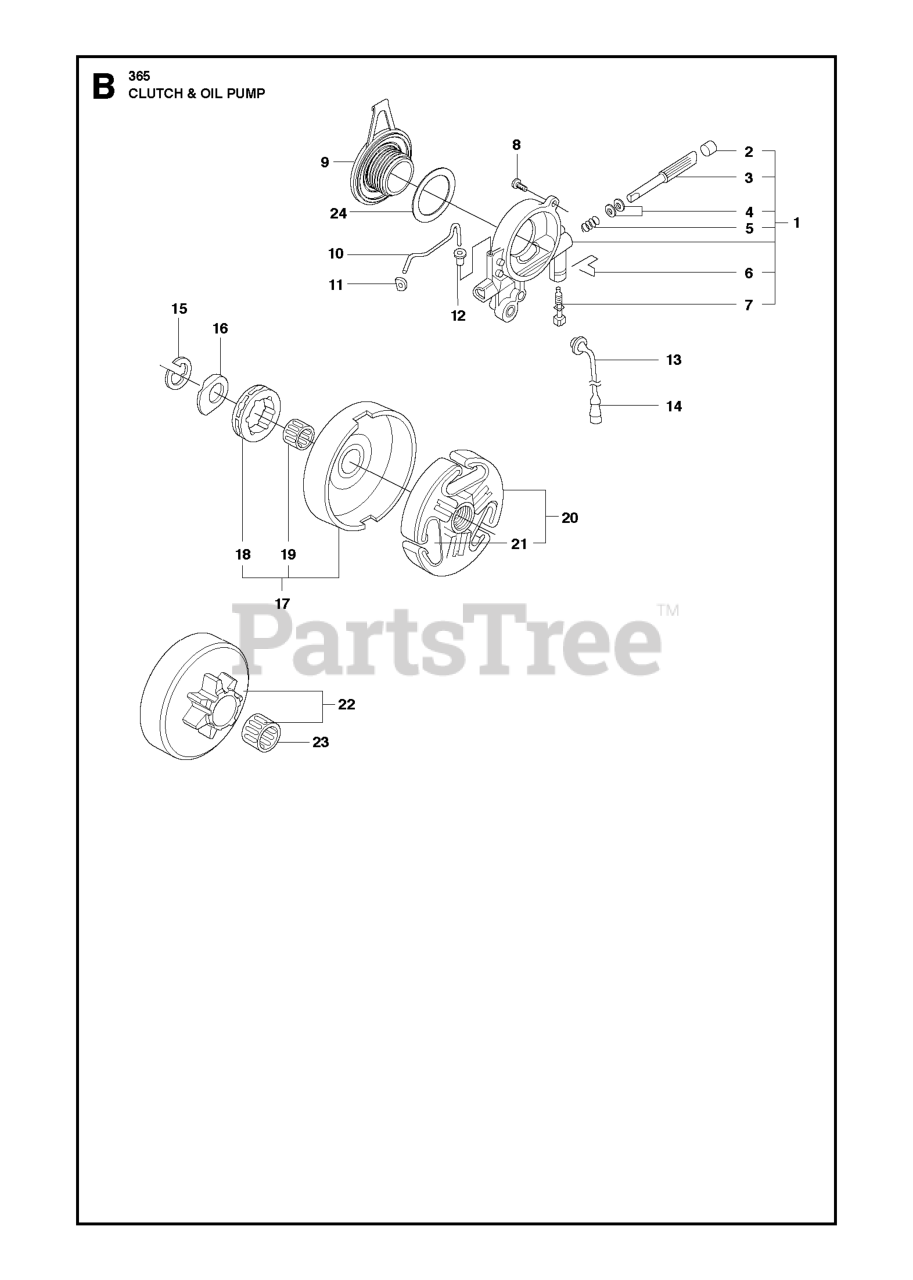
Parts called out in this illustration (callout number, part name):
1	OIL PUMP
3	PUMP PISTON
4	WASHER 6.1X9
6	SPRING CLIP
8	SCREW MC6S 5X16
9	OIL PUMP DRIVE
14	OIL SCREEN
15	RETAINING RING
17	CLUTCH DRUM
18	22273 Sprocket 3/8"x8T
18	68210 RIMSPROCKET
19	CLUTCH DRUM BEARING
20	CLUTCH
22	CLUTCH DRUM
23	CLUTCH DRUM BEARING
